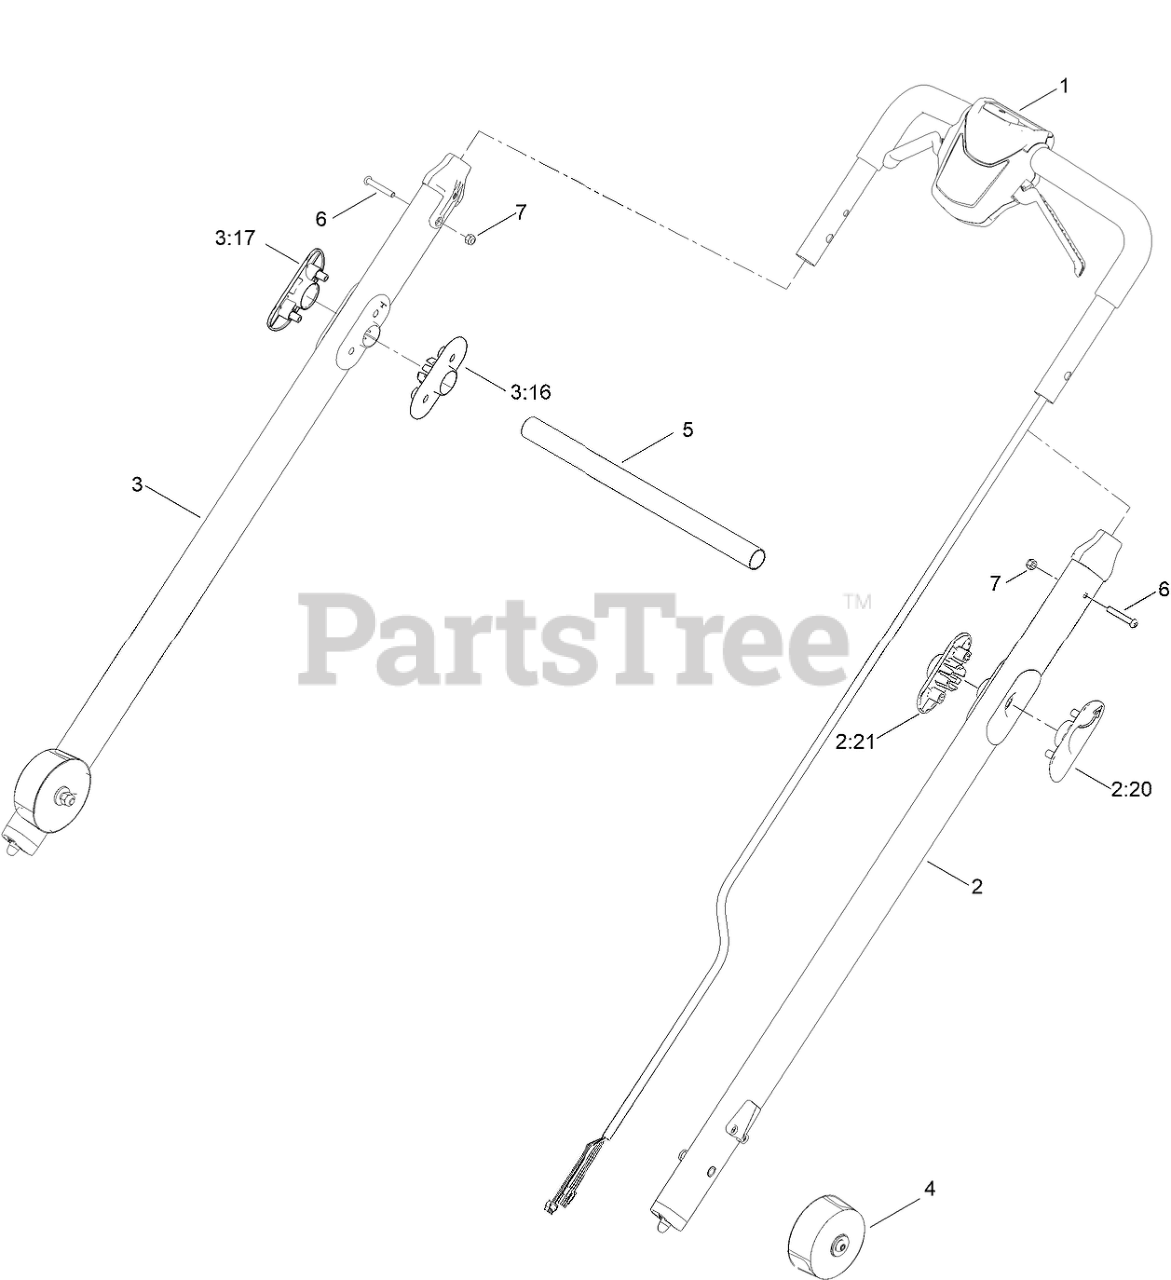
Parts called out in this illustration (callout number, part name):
1	HANDLEBAR CONTROL ASM, 36CM
2	HANDLEBAR ASM, LH
2:20	HANDLEBAR BRACE - INNER
2:21	HANDLEBAR BRACE, OUTER
3	HANDLEBAR ASM, RH
3:16	HANDLEBAR BRACE - INNER
3:17	HANDLEBAR BRACE, OUTER
4	HANDLEBAR END CAP
5	BRACE, HANDLEBAR RELEASE
6	BOLT, M6X40
7	NUT, M6, NYLOC
